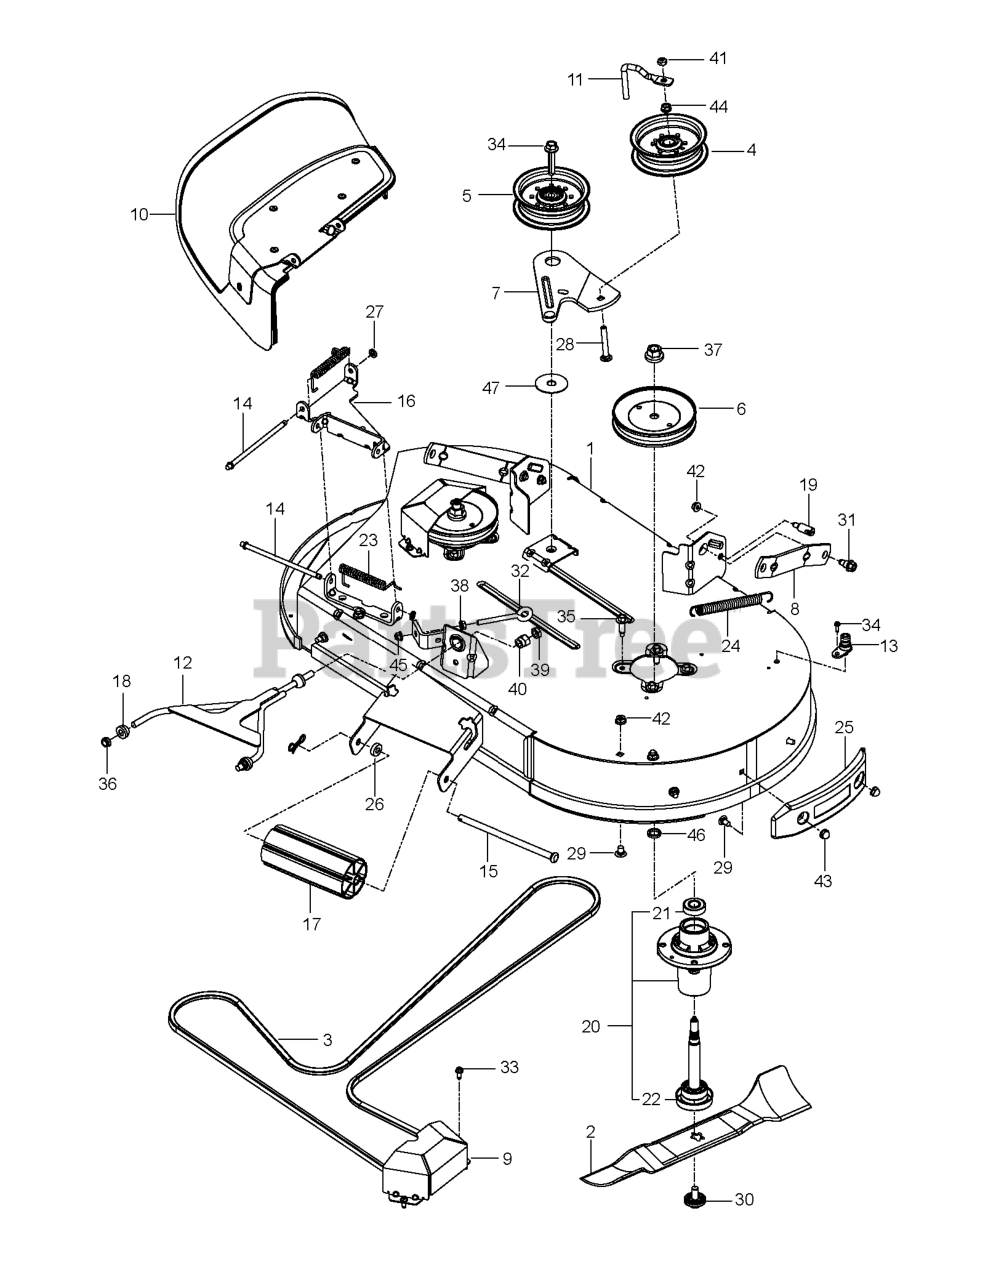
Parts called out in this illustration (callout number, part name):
1	HOUSING.ASM.PNT.42.WELL.ZTR
2	BLADE.42.FCS.BAGGING.BLADE.RAW
3	BELT.42.FCS.ZTR.DECK.DRIVE
4	PULLEY.IDLER.2006
5	PULLEY.IDLER.MWR.STATI.LH
6	PULLEY MANDREL 5.0"
7	ARM.42"FCS.CLUTCHING.X431
8	ARM.RFIXED.MOWER.SUSPNSIONX431
9	COVER.42".MANDREL.FCS X668
10	DEFLECTOR.ASM.42.FCS.ORANGE
11	KEEPER.BELT.IDLER.54"T
12	LINK.RZ.FRONT.WELDMENT.E-DIP
13	PORT.WASHOUT
14	ROD.HINGE
15	ROD.ROLLER.NOSE.NARROW.48"
16	BRACKET.42".FCS.DBLE.HINGEX668
17	NOSE ROLLER 48"
18	BUSHING SPHERICAL SUSP. FRONT
19	STUD.FASTNER.W/ANTI-ROTATE
20	MANDREL.DECK.ASSEMBLY
22	SHAFT ASM MANDREL
23	SPRING.42.FCS.DEFLECTOR
24	SPRING.MOWER.DRIVE.ELECTRIC
25	BUMPER.42CC.TRIM.SIDE.ASSY.HUS
26	BUSHING.NOSE.ROLLER
27	NUT PUSH M
29	BOLT.CARR.5/16-18X5/8.SHORT
30	BOLT.WASHER.ASM.7/16-2
31	BOLT.SHOULDER
32	EYE BOLT 5/16 X 3.50
33	SCREW.1/4-20X5/8
34	SCREW.7/16-14X2.125.HEX.WSH.HD
35	SCREW, WASHER HEAD
36	7/16-14 HEX NUT W/NYL RING ZD
37	NUT.FLANGE.LOCK.TOP
38	NUT 5/16C WHIZ
39	NUT **
40	NUT, LIFT LINK 7/16-20
41	NUT LOCK FLG 3/8-16 UNC
42	NUT LOCK HEX FLANGE 5/16-18
43	NUT ACORN,FLANGED,5/16-18
45	5/16-18 NYLOC FLANGE NUT
46	WASHER.SPACER.MANDREL
